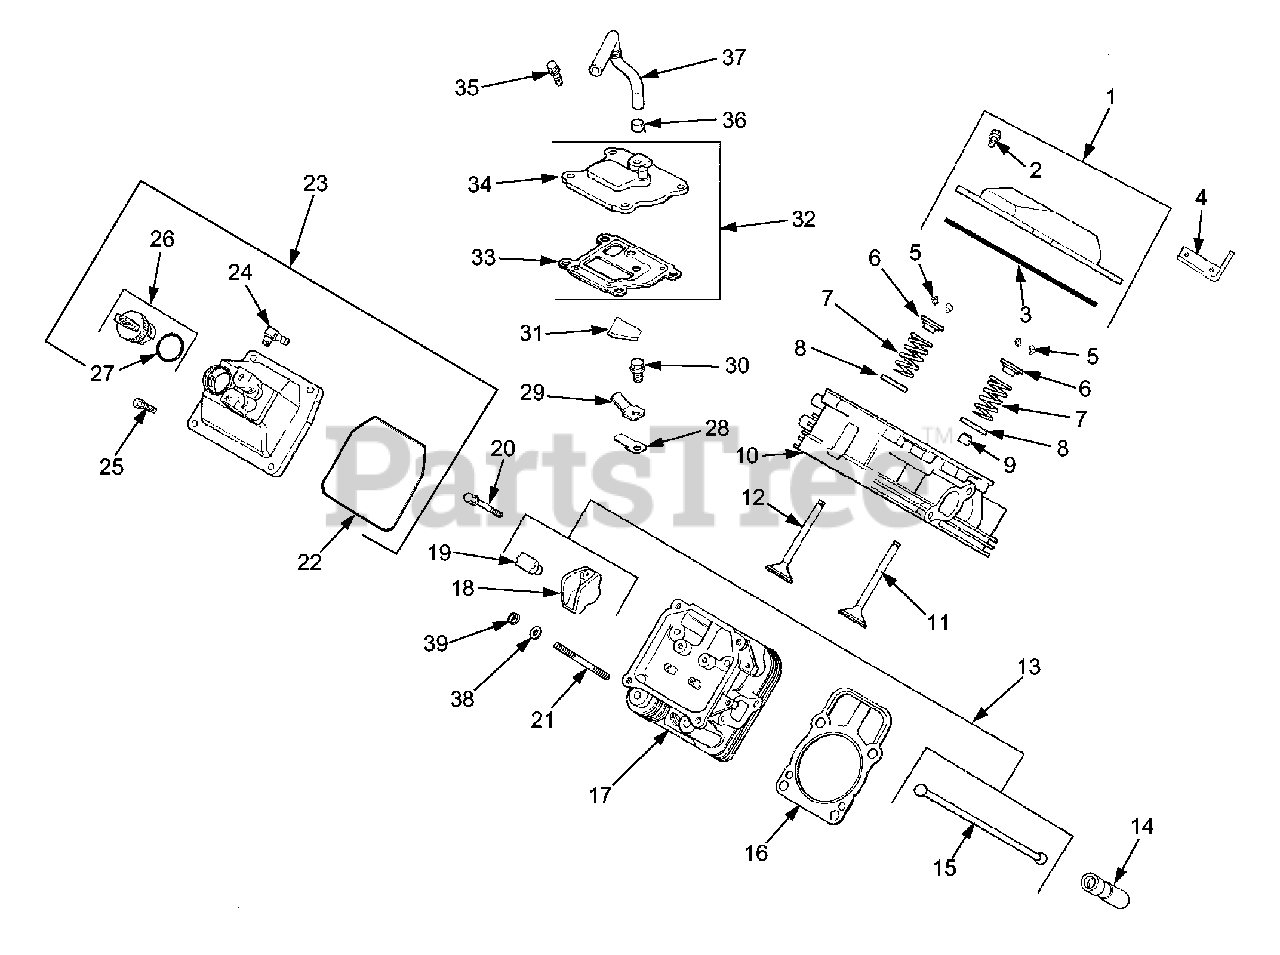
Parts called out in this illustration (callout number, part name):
1	Kit, Valve Cover
2	Screw, Shoulder
3	O-Ring, Valve Cover
4	Strap, Lifting
5	Kit, Retainer
6	Cap, Valve Spring
7	Spring, Valve
8	Retainer, Spring
9	Seal, Valve Stem
10	Head Assembly, #1 Cylinder
11	Valve, Intake (Std.)
12	Valve, Exhaust (Std.)
13	Kit, Valve Train
14	Lifter, Valve
16	Gasket, Kit, Cylinder Head
17	Head Assembly, #2 Cylinder
19	Pivot, Rocker Arm
20	Screw, Hex Flange M6 x 1 x 34
21	Stud, Cyl. Hd.
22	O-Ring, Valve Cover
23	Cover Kit, Fuel Pump Valve
24	Connector 90°
25	Screw, Shoulder
26	Cap Assembly, Oil Fill
27	O-Ring
28	Reed, Breather
29	Retainer, Breather Reed
30	Screw, Hex Flange M5 x 0.8 x 10
31	Filter, Breather
32	Kit, Breather
33	Gasket, Breather
34	Cover, Breather
35	Screw, Hex Flange M6 x 1.0 x 20
36	Clamp, Breather
37	Hose, Breather
38	Washer, Flat, 8mm
39	Nut, Hex Flange, M8 x 1.25
